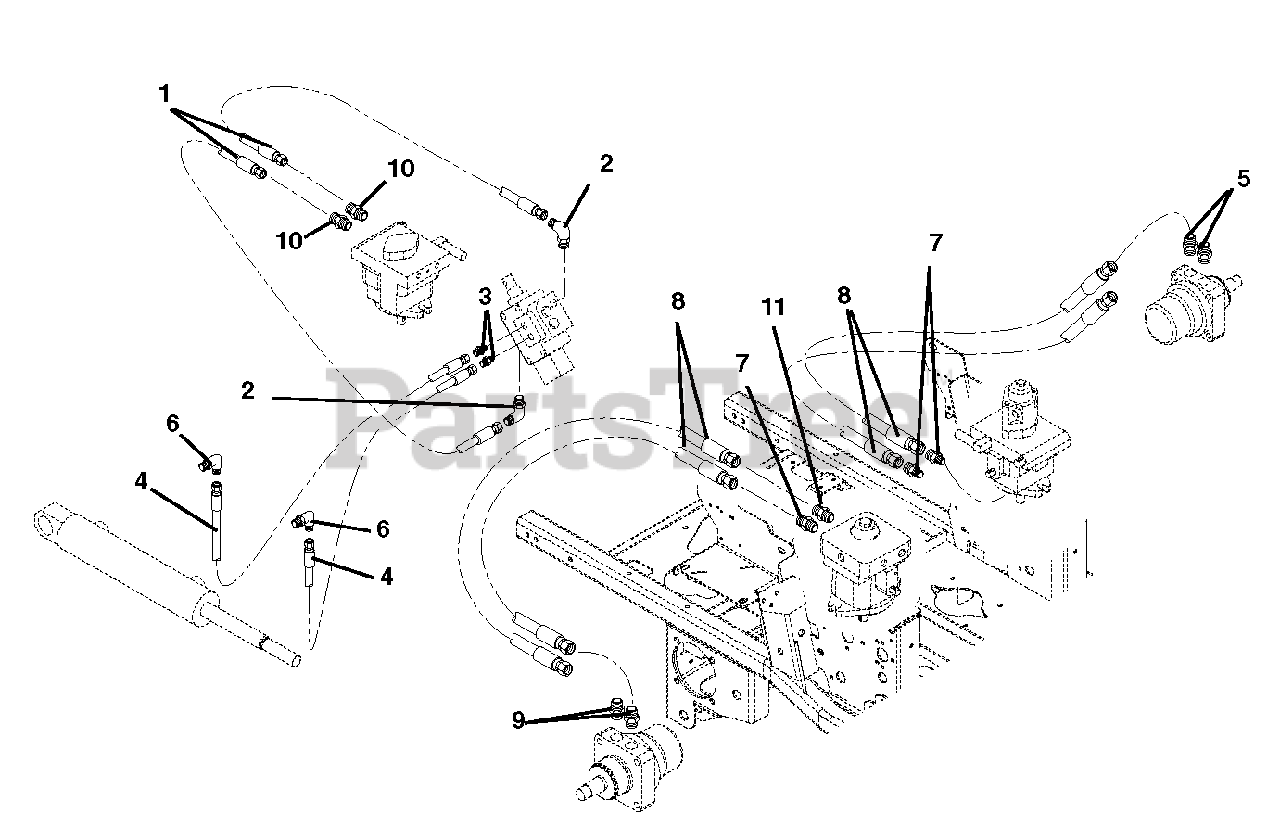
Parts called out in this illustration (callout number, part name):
1	Hose, Hydraulic (992150, 154, 159, 163, 164, 166, 167, 168, 170, 172)
2	Hydraulic, Fitting Elbow (992150, 154, 159, 163, 164, 166, 167, 168, 170, 172)
3	Adapter (4-6F5OLO) (992150, 154, 159, 163, 164, 166, 167, 168, 170, 172)
4	Hose, Hydraulic (992150, 154, 159, 163, 164, 166, 167, 168, 170, 172)
5	Fitting, Hyraulic Straight (8-10 F5OLO-S) (992150, 154, 159, 163, 164, 166, 167, 168, 170, 172)
6	Fitting, Hydraulic (4 C5OLO) (992150, 154, 159, 163, 164, 166, 167, 168, 170, 172)
7	Adapter, Face Seal 8 x 8 .50 O-Ring
8	Hose, Hydraulic .50
9	Adapter, Hydraulic Steel (M10 O-M8F)
10	Fitting, Hydraulic (4 F5OLO) (Supplied with pump) (992150, 154, 159, 163, 164, 166, 167, 168, 170, 172)
11	Fitting,Hydraulic 45 Degree M8F-M80
